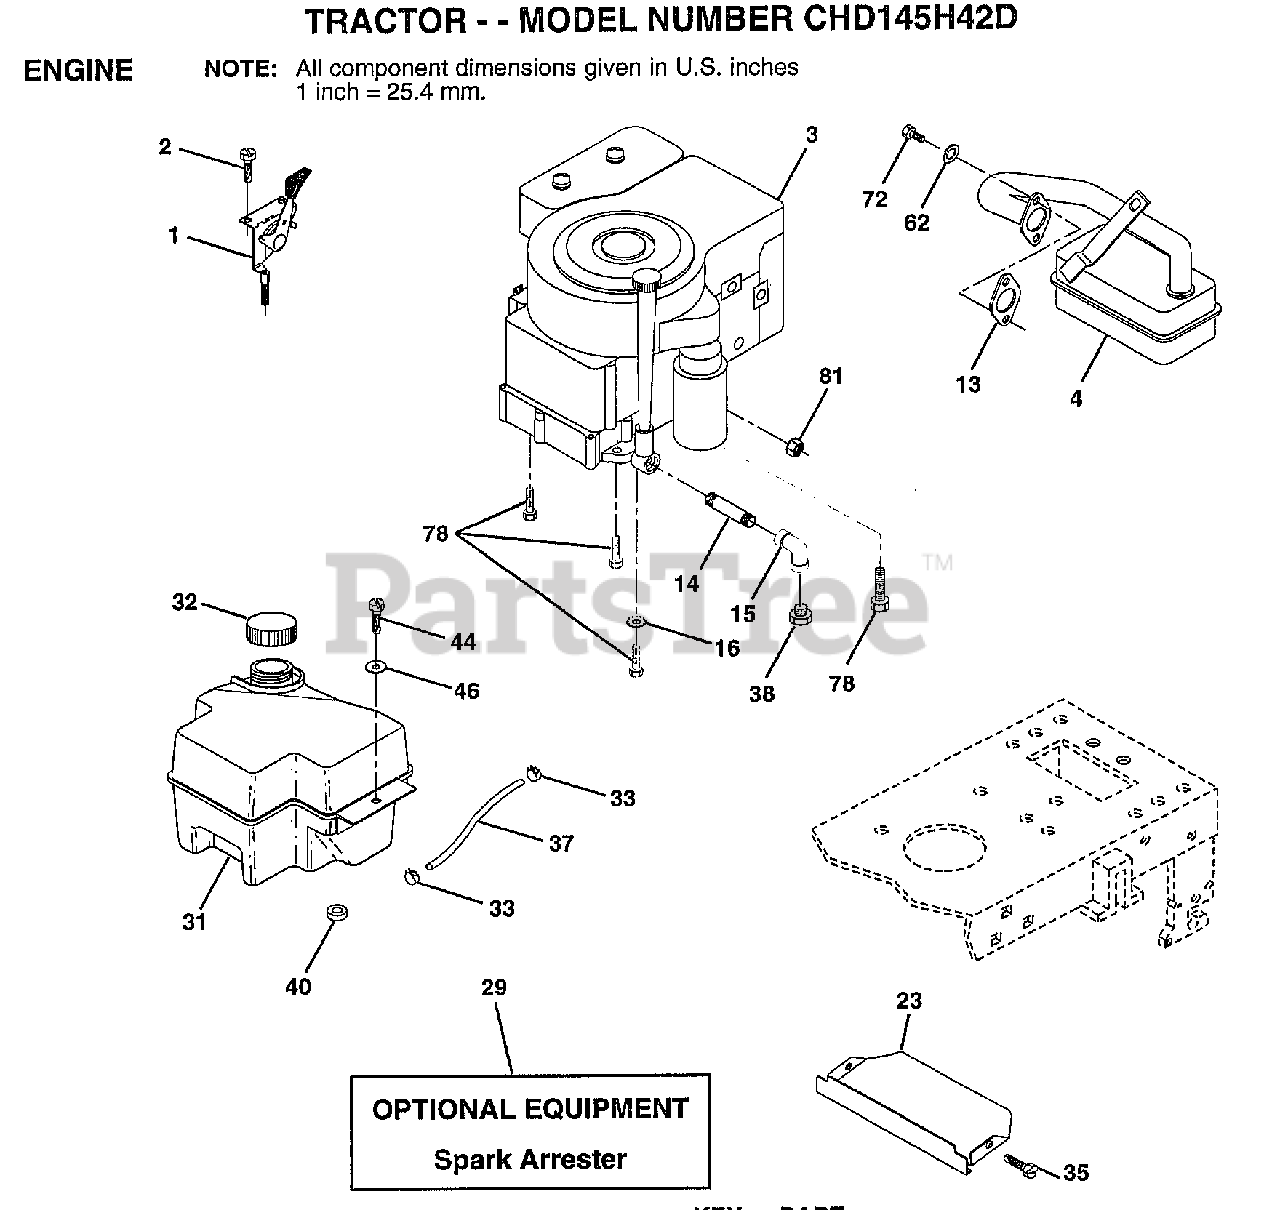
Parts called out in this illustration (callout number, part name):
1	CONTROL THROTTLE
2	SCREW LT
4	MUFFLER
13	GASKET ENG 1 313 LD TIN PLATED
14	PIPE NIPPLE
15	ELBOW
16	LOCKWASHER
23	SHIELD.BRN/DBR.GD
31	TANK.FUEL.FRONT.
32	CAP ASM FUEL
33	HOSE CLAMP
35	SCREW
37	LINE FUEL
44	SCREW HEX CRT
46	WASHER
62	LOCKWASHER
72	SCREW
78	SCREW
81	NUT
